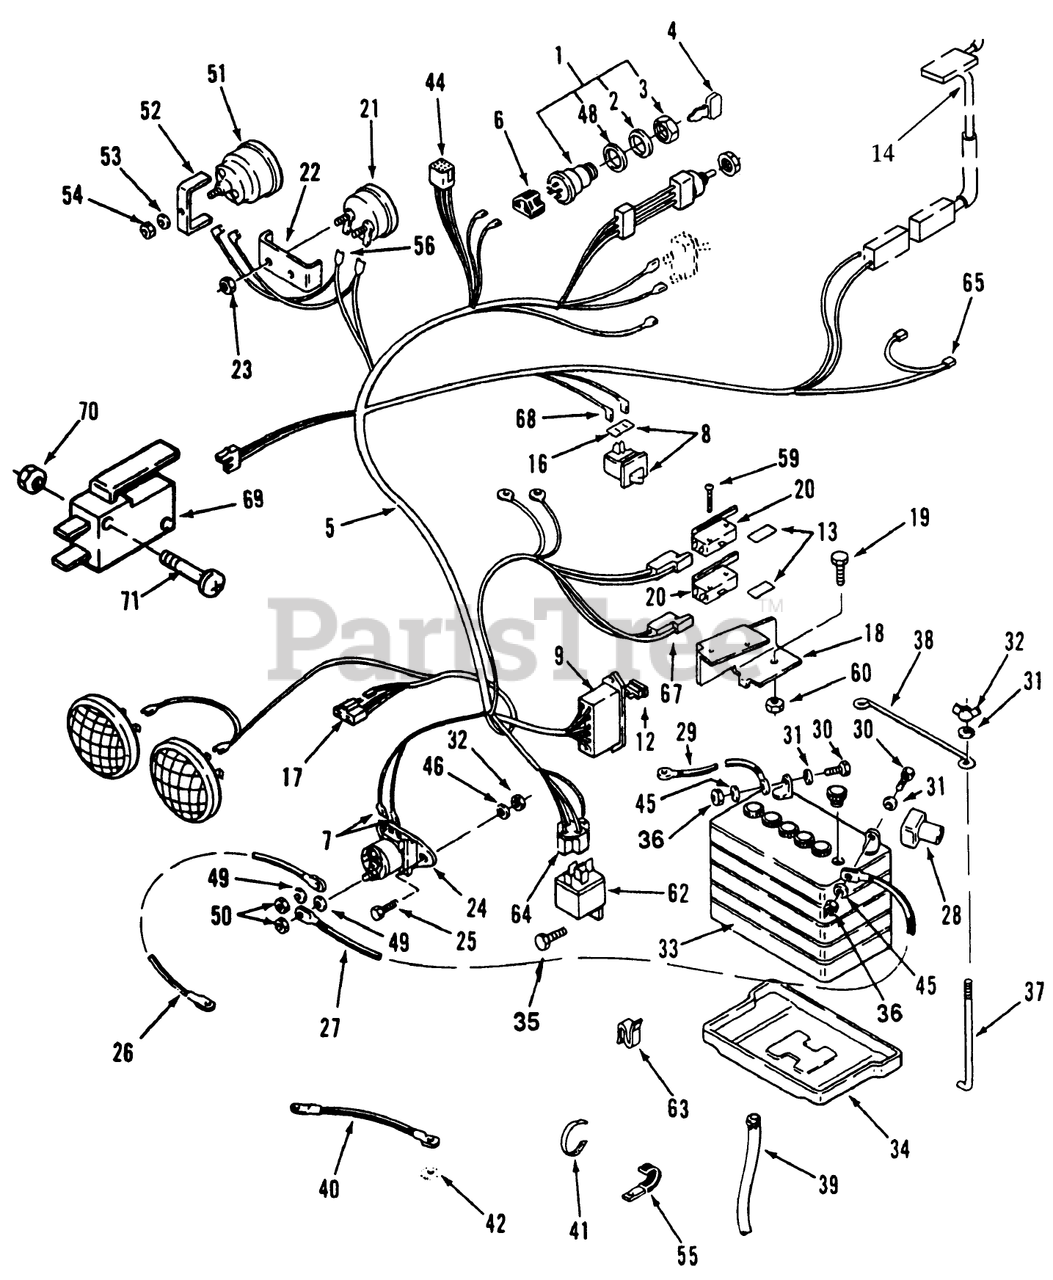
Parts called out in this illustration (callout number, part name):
1	KEY SWITCH ASM
4	KEY-IGNITION
6	CONNECTOR BODY ELECT
7	TERMINAL 10
12	FUSE-BLADE, 15 AMP
13	BARRIER - SWITCH
14	SWITCH-SEAT
16	SHIELD-DIRT SPST
17	5-CONTACT CONN BODY
19	Bolt
20	SWITCH
21	VOLTMETER
22	CLAMP-MOUNTING
23	HEX NUT 10-32 E.S. + + USE 3296-21 + +
27	CABLE-BLACK
30	SCREW-HH
31	WASHER-FLAT
34	TRAY-BATTERY
37	HOOK-BATTERY RETAIN
38	HOLDDOWN-BATTERY
39	TUBE-21" BATTERY DRAIN
40	WIRE GROUND
42	WASHER-LOCK, INTERNAL
45	WASHER-LOCK
49	WASHER-LOCK
50	NUT-JAM
52	BRKT-GAUGE MOUNTING
55	CLIP
62	RELAY
63	CLIP-CABLE
64	TERMINAL 10
65	Sur-Plug
68	Terminal
69	SWITCH
